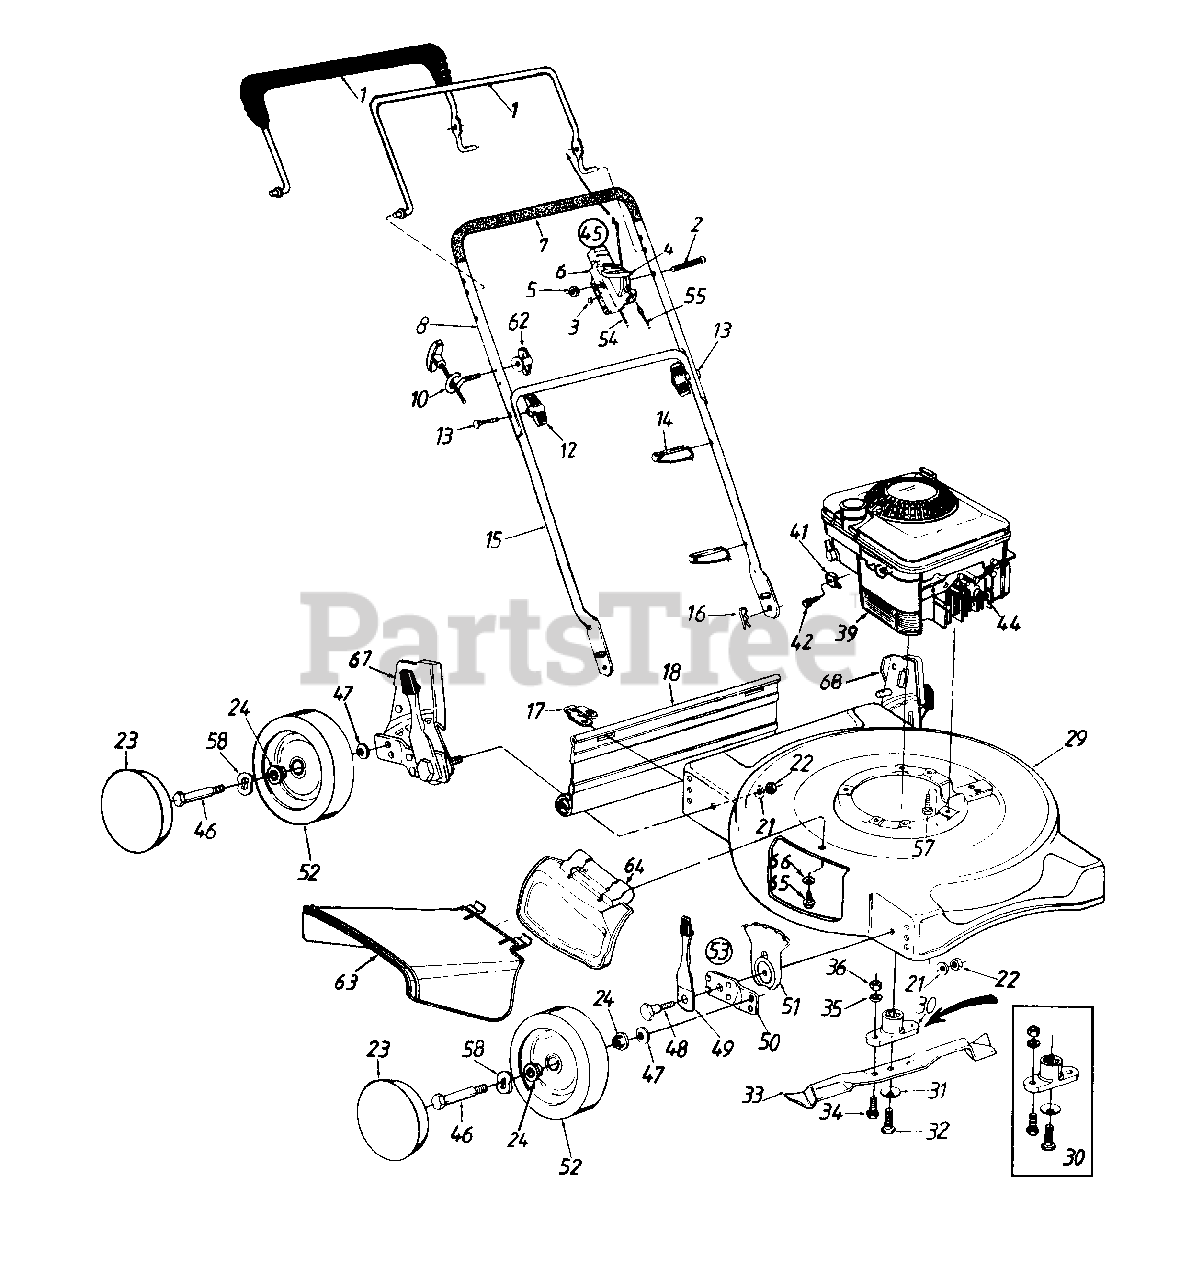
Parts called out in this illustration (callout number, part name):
1	Control Handle Ass'y.
2	Oval C-Sunk Scr.
3	Spr. Wash. .66" I.D.
4	Throttle Lever
5	Hex L-Nut 1/4-20 Thd.
6	Throttle Body
7	Grip
12	Hand Knob
13	Curved Hd. Bolt 5/16-18 x 2" Lg.
14	Cable Tie
16	Hairpin Cotter
17	Hinge Clip
18	Rear Flap
21	Bell-Wash. .39" I.D. x 1.38"
22	Hex Nut 3/8-16 Thd.
23	Hub Cap
24	Bearing
29	20" Deck Ass'y.
30	Blade Adapter Kit
31	Bell-Wash. .39" I.D.
32	Hex Bolt 3/8-24 x 1.5" Lg.
33	20" Mulching Blade
34	Hex Bolt 3/8-24 x 1" Lg.
35	L-Wash. 3/8" I.D.
36	Hex Nut 3/8-24 Thd.
39	Engine
41	Cable Clamp
42	Hex Self-Tap Scr. #10-32 x .62"
44	Spark Plug Boot
45	Throttle Box Comp.
46	Axle Bolt
47	Bell-Wash. .400" I.D. x .88"
48	Shld. Bolt .50" Dia. x .357"
49	Spring Lever Ass'y. w/Knob
51	Height Adj. Plate
52	Wheel Ass'y. Comp.
53	Height Adj. Ass'y. Comp. - R.F.
54	Throttle Cable - 51"
55	Control Cable - 39"
57	Hex L-Wash. Hd. Scr. 3/8-16 x 1.0" Lg.
58	Wave Washer .51" I.D.
62	Handle Knob 1/4-20 Thd.
63	Chute Deflector
64	Mulching Plug
65	Hex Wash. Hd. TT-Tap Scr. 1/4-20 x .5" Lg.
66	Bell-Wash. 1/4" I.D.
